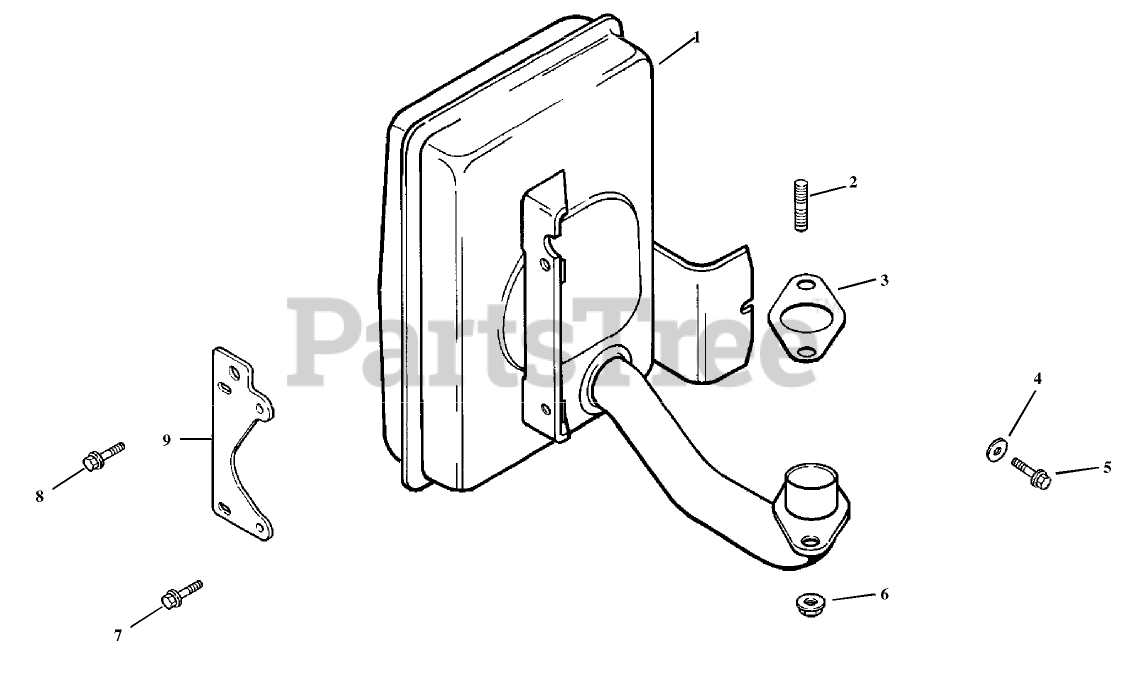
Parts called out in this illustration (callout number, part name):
1	Muffler
2	STUD (M8X1.25X33)
3	Gasket-Manifold, Exhaust
4	Washer-Plain (1/4in)
5	SCREW-FLANGE, THREAD FORMING (M5X0.8X16)
6	NUT-FLANGE (M8X1.25)
7	SCREW-FLANGE, THREAD FORMING (M6X1.0X16)
8	SCREW-FLANGE, THREAD FORMING (M6X1.0X25)
9	Bracket-Muffler
